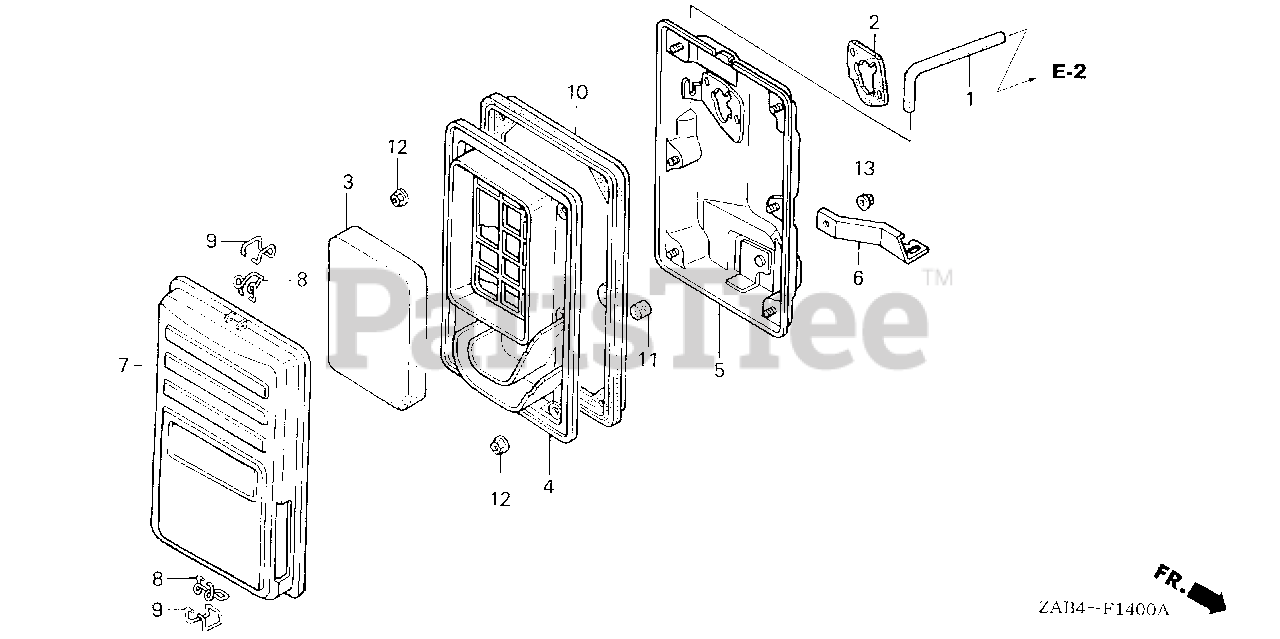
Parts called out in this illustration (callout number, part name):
1	TUBE, BREATHER
2	SPACER, CARBURETOR
3	ELEMENT, AIR CLEANER
4	SEPARATOR, AIR CLEANER
5	HOUSING, AIR CLEANER
6	STAY, AIR CLEANER
7	COVER, AIR CLEANER
8	CLIP A, AIR CLEANER WIRE
9	CLIP B, AIR CLEANER WIRE
10	SEAL, AIR CLEANER
11	FILTER, DRAIN TUBE
12	NUT, FLANGE (5MM)
13	NUT, FLANGE (6MM)
